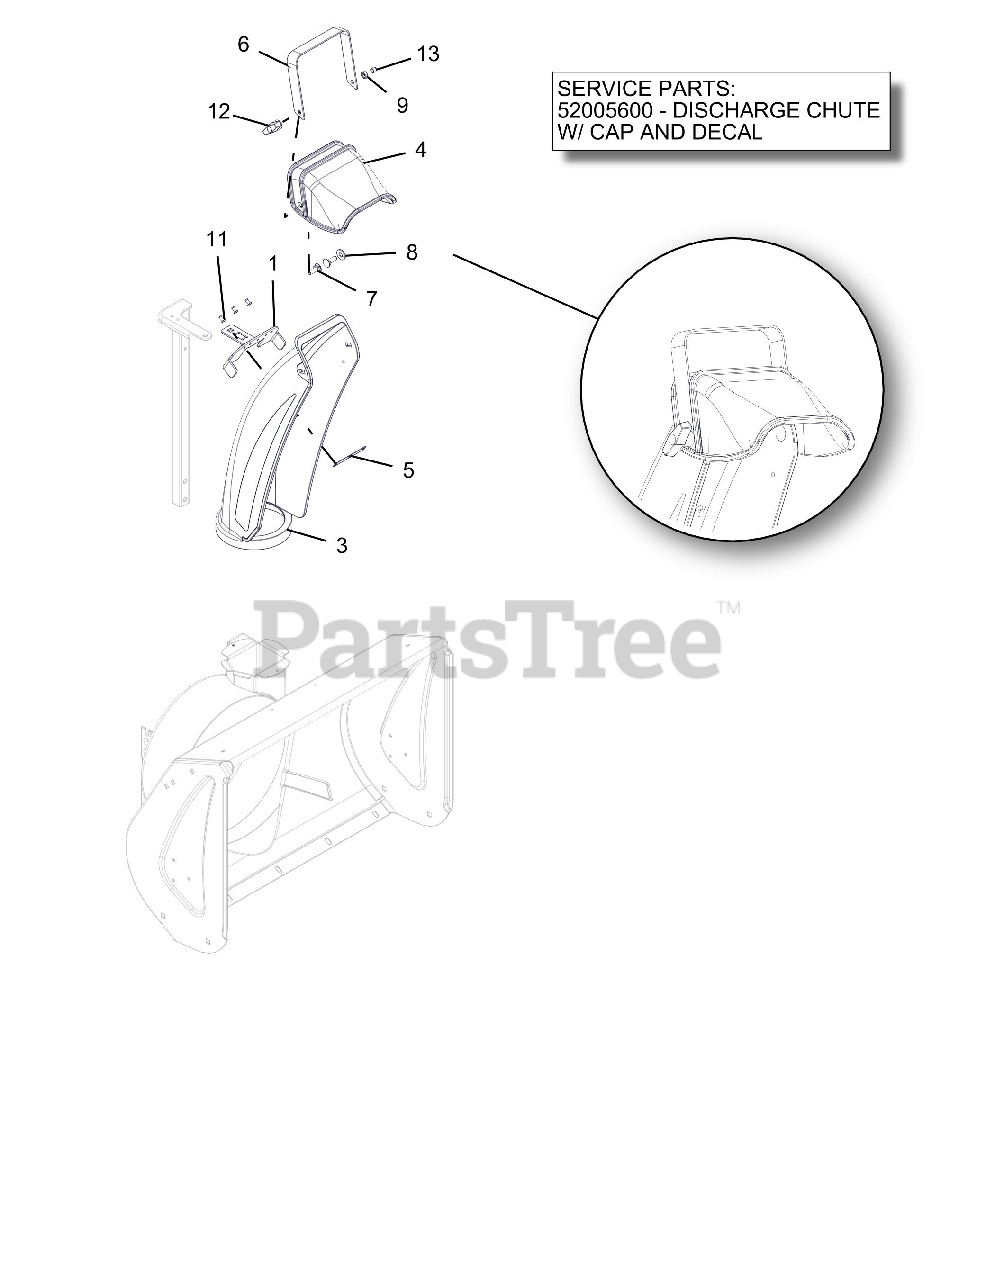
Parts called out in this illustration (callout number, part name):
1	CHUTE MOUNT BRACKET
3	CHUTE, PLASTIC DISCHARGE LONG
4	DEFLECTOR CAP, PLASTIC
5	PLATE,CHUTE MOUNT BACKING
6	HANDLE, MANUAL CHUTE CAP
7	BLT,RNHDRECSHNK .31-18X1.00
8	@WSHR-FL-STL.38X.875X.083 YWZC
9	@NUT-LK-CTR-JAM .31-18 YWZC
11	RIVET, #66 STEEL POP PD BLACK
12	KNOB, WING .31-18 UNC
13	CAP, END .281X.313
14	CHUTE, MANUAL DISCHARGE W/CAP
